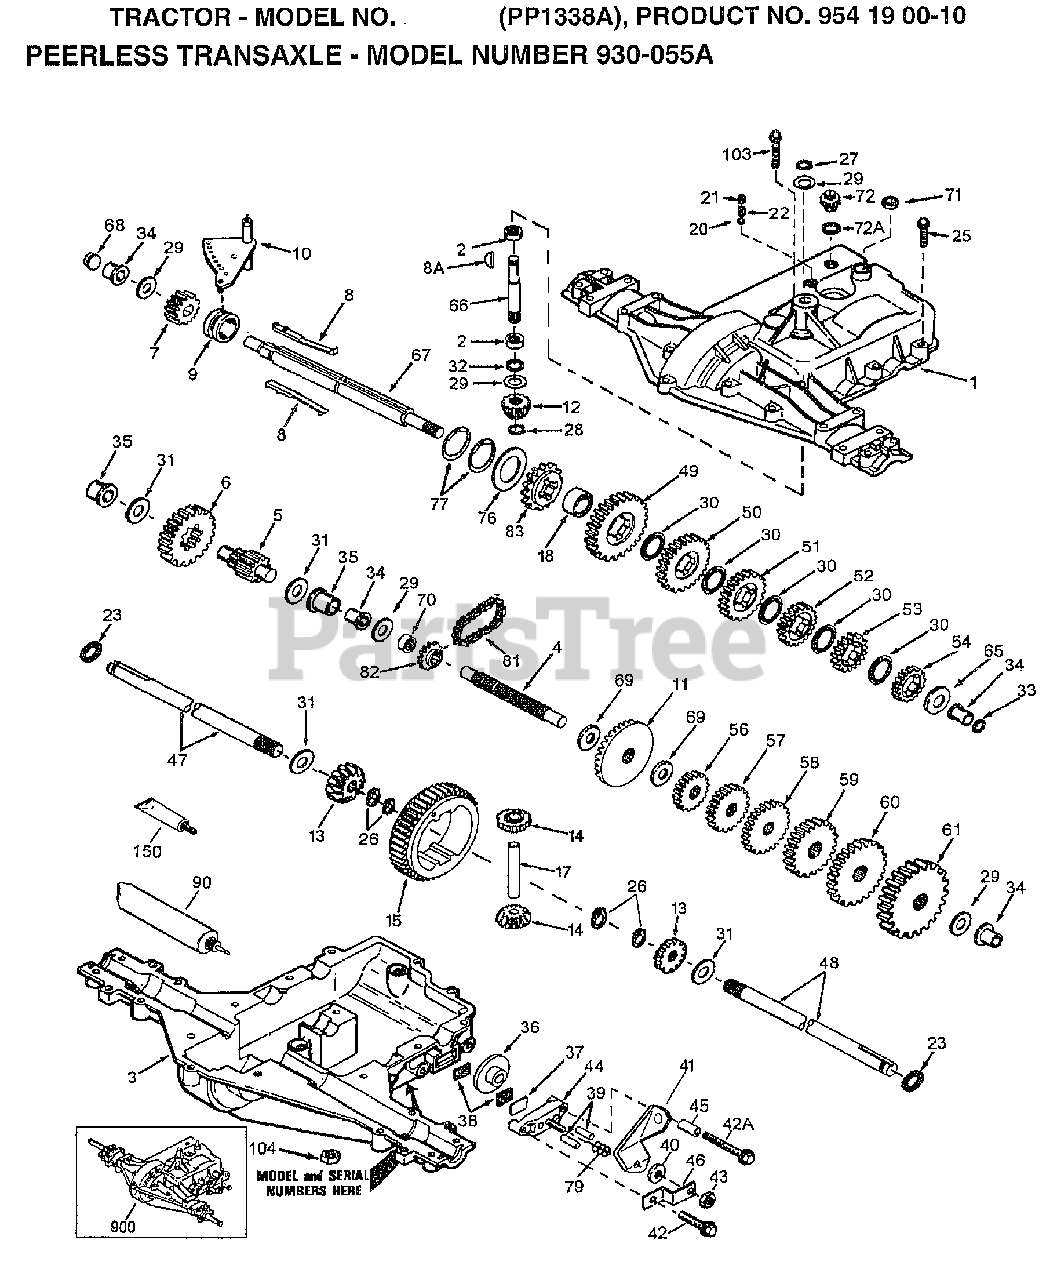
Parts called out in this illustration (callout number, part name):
1	TRANSAXLE COVER
2	BEARING, NEEDLE
3	TRANSAXLE CASE
4	SHAFT, COUNTER
5	OUTPUT SHAFT AND PINION
6	GEAR, OUTPUT
7	GEAR, SPUR, 15 TEETH
8A	KEY, WOODRUFF
9	COLLAR, SHIFTER
10	ROD & FORK ASSY, SHIFT
11	GEAR, BEVEL, 42 TEETH
12	BEVEL PINION, INPUT
13	GEAR, BEVEL
14	GEAR, BEVEL, PINION
18	SPACER, NEUTRAL
20	BALL STEEL, 5/16" DIA.
21	SCREW, 3/8-16 X 3/8"
25	SCREW, 1/4-20 X 1-1/4
26	RING RETAINER
27	RING, RETAINER
28	RETAINING RING
29	WASHER THRUST
30	WASHER THRUST
33	SEAL, SQUARE CUT
34	BUSHING, FLANGED
35	BUSHING, FLANGED
36	DISK, BRAKE
37	PLATE BRAKE PAD
41	BRAKE LEVER
42	SCREW, 1/4-20 X 1-1/4
42A	SCREW, 1/4-20 X 2-1/4
43	LOCKNUT 5/16-24
44	HOLDER BRAKE PAD
46	BRKT BRAKE LEVER
49	GEAR, SPUR, 37 TEETH
50	GEAR, SPUR, 35 TEETH
51	GEAR, SPUR, 30 TEETH
52	GEAR, SPUR, 25 TEETH
53	GEAR, SPUR, 22 TEETH
54	GEAR, SPUR, 19T
56	GEAR, SPUR, 12 TEETH
57	GEAR, SPUR, 15 TEETH
58	GEAR, SPUR, 20 TEETH
59	GEAR, SPUR, 25 TEETH
60	GEAR, SPUR, 28 TEETH
61	GEAR, SPUR, 31 TEETH
65	WASHER, THRUST
66	SHAFT, INPUT
67	SHAFT, BRAKE, 4 KEYED
69	WASHER THRUST
71	SEAL SQUARE CUT
72	THREADED PLUG 9/16-18
76	WASHER, THRUST
77	INVERTED RETAINING RING
81	CHAIN, ROLLER
82	SPROCKET 9T
83	SPROCKET 18T (REV)
90	GREASE BENTONITE, 32 OZ.
150	GASKET ELIMINATOR
900	REPLACEMENT TRANSAXLE
